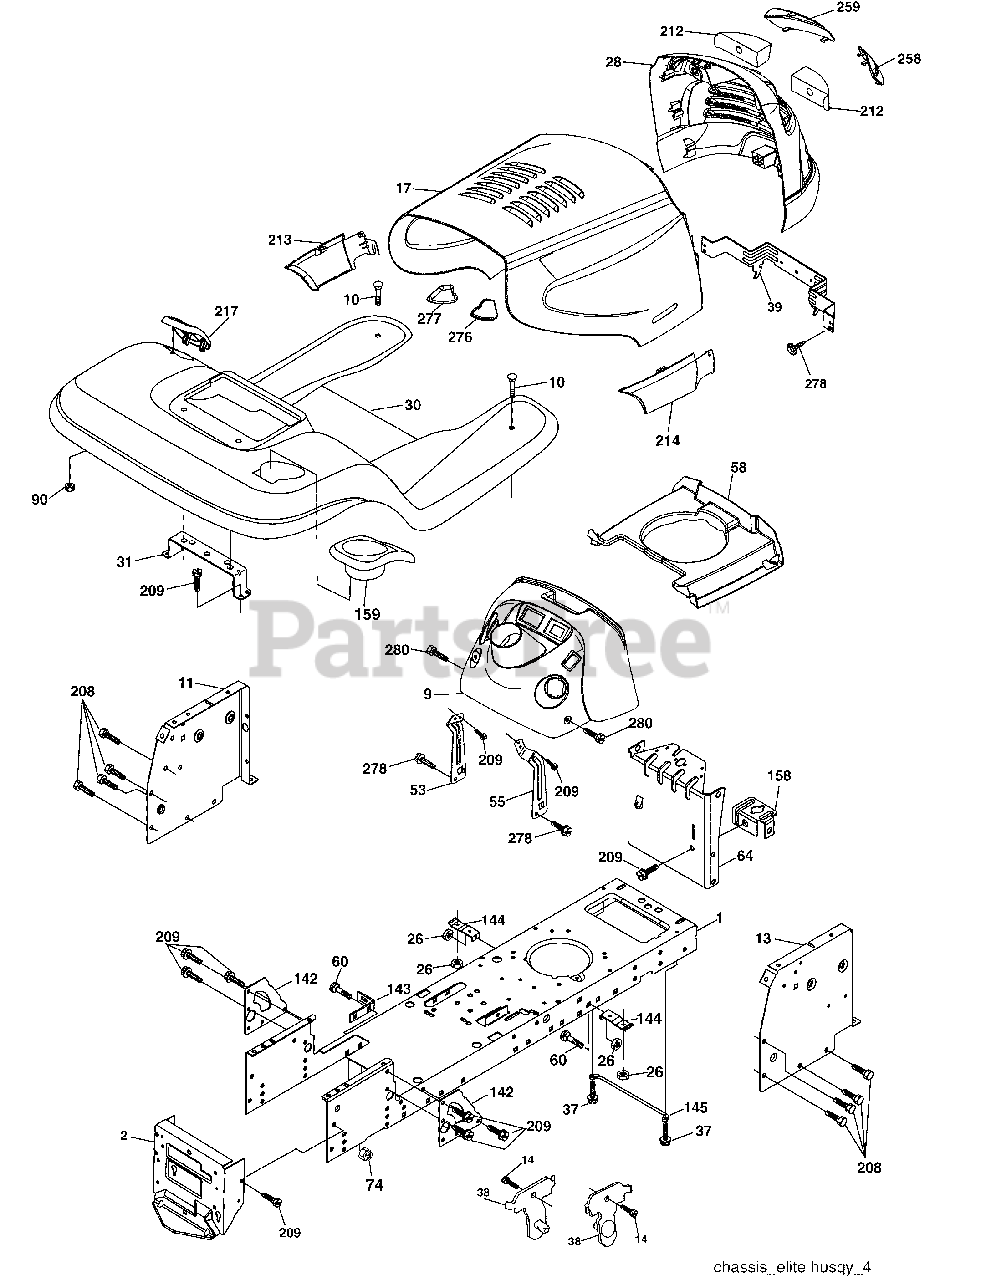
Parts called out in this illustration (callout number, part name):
1	Chassis Stamping
9	Dash P/L M
10	Bolt Carriage 3/8-16 x 1
11	Panel Dash Lh
13	Panel Dash Rh
14	Screw Thdrol 3/8-16 x 1/2
17	Hood
26	Nut Lock Hex W/Ins 3/8-16 unc
28	Grille/Lens Asm.
30	Fender Footrest STLT Pnt
31	Bracket Support Fender
37	Screw Thdrol 5/16-18 x 1/2 TYT
38	Bracket Asm Pivot Mower Rear
39	Bracket Pivot
53	Bracket Dash LH
55	Bracket Dash RH
58	Air Duct Engine
60	Bolt Rdhd Sqnk 3/8-16 unc x 3/4
64	Dash Lower STLT
74	Nut Crownlock 3/8-16 unc
90	Nut Self-thd Wsh-Hd 1/4
142	Plate Reinforcement STLT
143	Bracket Swaybar Chassis
144	Bracket Pnt Footrest STLT
145	Rod Pivot Chassis/Hood
158	Bracket Parking Brake
159	Cupholder
208	Screw Thdrol 3/8-16 x 1/2 TYT Bl
209	Screw 3/8-16 x 3/4
212	Insert Lens Reflect
213	Skirt Side LH
214	Skirt Side RH
217	Console Fuel Window
258	Lens RH
259	Lens LH
276	Bumper Hood RH
277	Bumper Hood LH
278	Screw 10 x 3/4 Single Lead Hex
280	Screw 3/18-16 x 1
